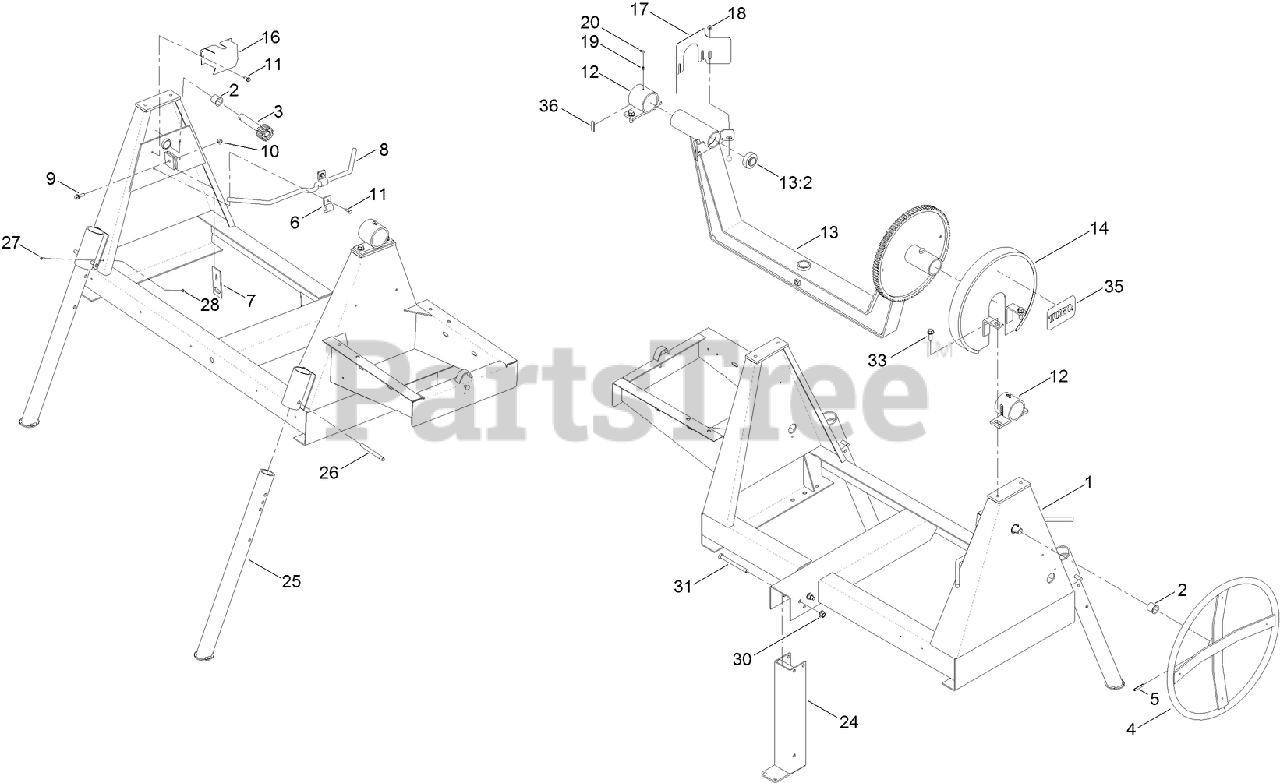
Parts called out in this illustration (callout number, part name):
2	BUSHING-NYLON
3	SHAFT-TILT
4	HANDWHEEL
5	PIN-ROLL
6	BRACKET-HANDLE
7	DOG-BRAKE
8	HANDLE-BRAKE
9	SCREW-HHF
10	NUT-HF, NI
11	SCREW-THD ROLL, HWH
12	TRUNNION
13	YOKE ASM
13:2	Bearing
14	GUARD-BRAKE, UPPER
16	GUARD-BRAKE, LOWER
17	GUARD-PINION
18	NUT-HF, NI
19	FITTING-GREASE
20	CAP-PLUG
24	POST-FOOT
25	LEG-STABILIZER
26	PIN-CLEVIS, LANYARD
27	SCREW-PPH
28	NUT-LOCK, NI
30	NUT-LOCK
31	SCREW-HH
33	SCREW-HWH
35	DECAL
36	DECAL-GREASE
